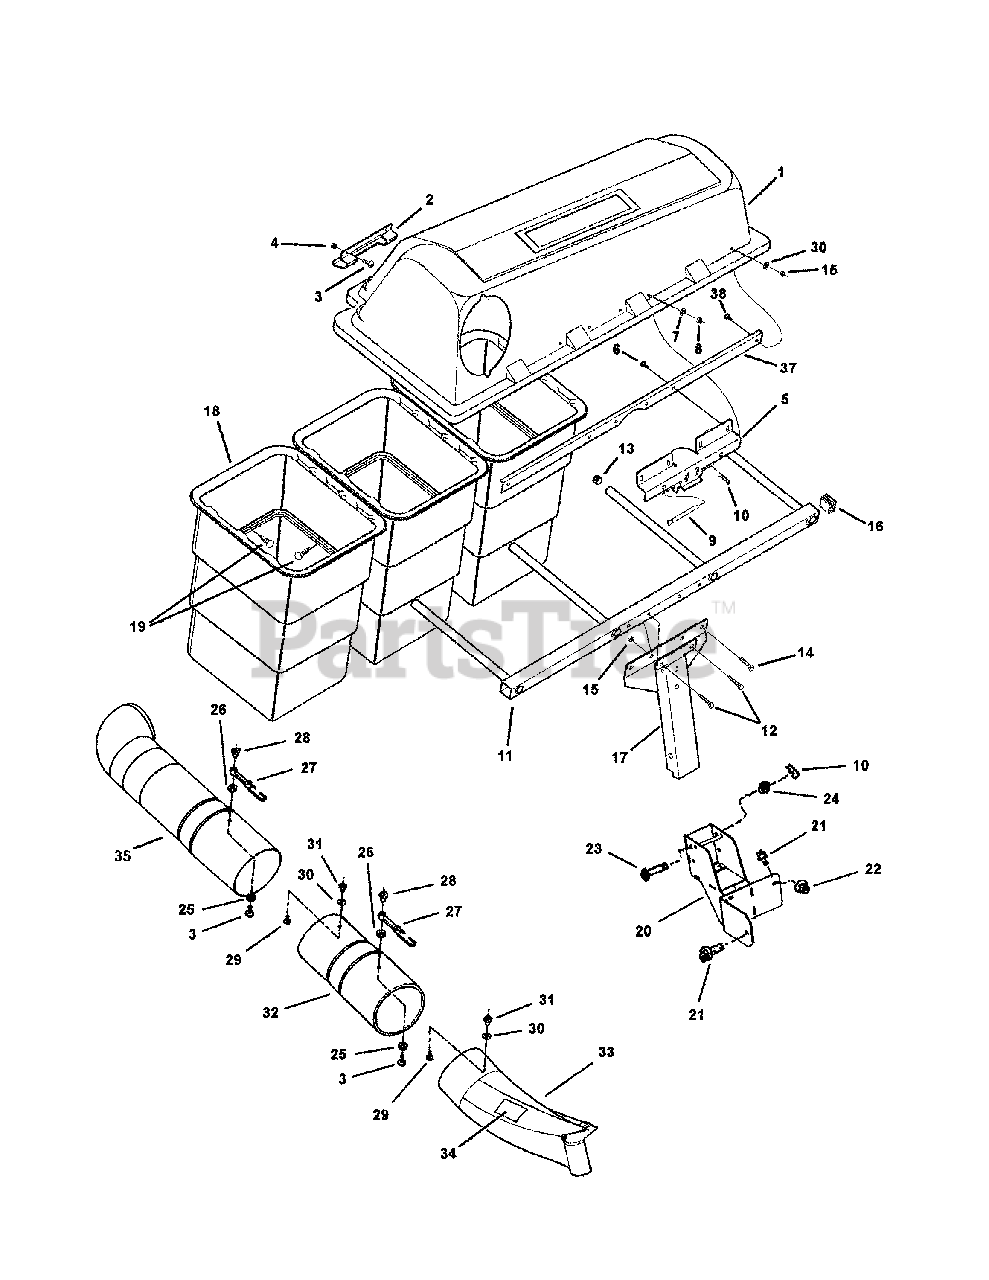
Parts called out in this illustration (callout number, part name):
1	TRIPLE COVER ASSEMBLY, 44/50"
2	HANDLE. Cover
3	SCREW, Cross Recessed Pan Head, 10 - 24 x 5/8
4	NUT, Hex Lock, 10 - 24
5	HINGE, Cover
6	BOLT, Carriage, 1/4 - 20 x 3/4
7	WASHER, SAE, 1/4
8	NUT, Hex Center Lock, 1/4 - 20
9	PIN, Cover Hinge
10	PIN, Hair, 3/32 x 1-1/2
11	WELDMENT, Triple Catcher Frame
12	SCREW, Hex Head Cap, 5/16 - 18 x 2-1/4
13	PLUG, Round
14	SCREW, Hex Head Cap, 5/16 - 18 x 2
15	NUT, Hex Center Lock, 5/16 - 18
16	PLUG, Square
17	WELD, Channel Support, Triple
18	CONTAINER, Nestable Triple Catcher
19	FASTENER, Panel
20	WELDMENT, Grass Catcher Support
21	BOLT, Hex Washer Self-Tap, 5/16 - 18 x 3/4
22	NUT, Flange, 5/16 - 18
23	PIN, Clevis
24	WASHER, SAE, 1/2
25	WASHER, SAE, 7/32 x 1/2
26	WASHER, SAE, 3/16 x 3/4
27	STRAP, Mounting Bag Adapter/Tube
28	NUT, Tee, 10-24
29	SCREW, Pan Head Torx, 5/16 - 18 x 5/8
30	WASHER, SAE, 5/16
31	NUT, Tee, 5/16 - 18
32	TUBE, Lower
33	ADAPTER, Bag
34	DECAL, Warning
35	TUBE, Upper
37	BRACE, Cover
38	BOLT, Carriage, 5/16 - 18 x 3/4
